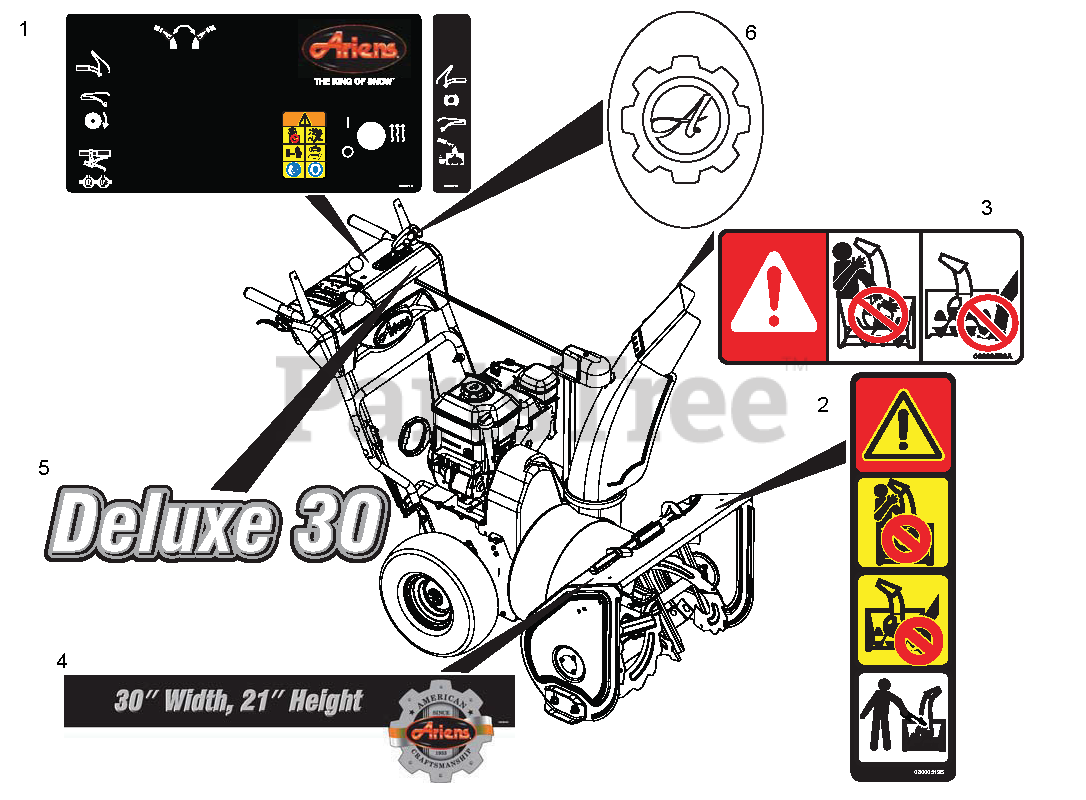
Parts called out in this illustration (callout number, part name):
1	DECAL, CONTROL - DLX PIN-LOCK
1	DECAL,CONTROL - DLX REMOTE AXL
1	DECAL, CONTROL - DELUXE TRACK
1	DECAL, CONTROL - DLX TRACK HW
1	DECAL,CONTROL - DLX REM AXL,HW
1	DECAL,CTRL,CRNK,REMOTE,AUTODIF
1	DECAL, CONTROL - PLATINUM/PRO
1	DECAL,CTRL,HW,CRNK,REM,AUTODIF
2	DECAL, DANGER - ROTATING PARTS
3	DECAL, DANGER
5	DECAL, DELUXE 30
5	DECAL, PLATINUM 24
5	DECAL, PLATINUM 30
5	DECAL, DELUXE 28 SM DASH
5	DECAL,ST24 DELUXE-COMPACT DASH
6	DECAL, ARIENS GEAR - RAISED
